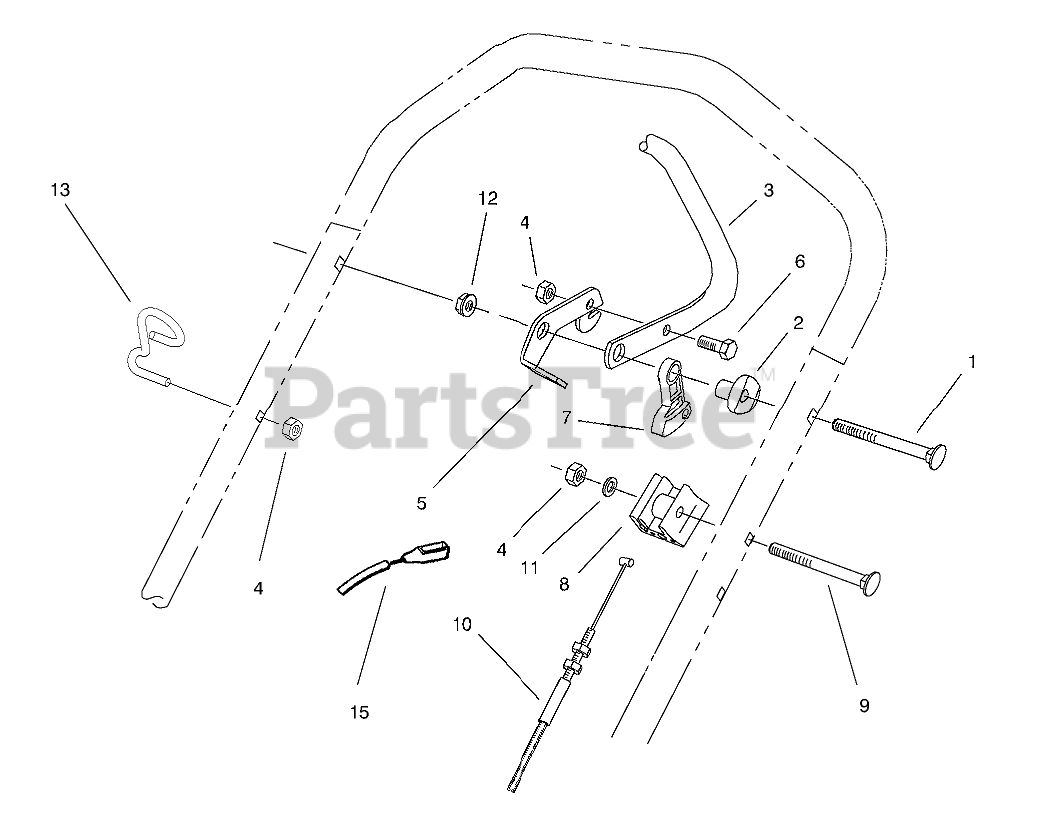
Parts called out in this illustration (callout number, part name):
1	SCREW-HANDLE
2	SPACER-SUPPORT
3	Bar-Control
4	NUT-LOCK, NI
5	LEVER-CONTROL
6	SCREW-HH
7	LEVER-TRACTION
8	SUPPORT-CABLE
9	SCREW-HANDLE
10	CABLE-TRACTION
11	WASHER-FLAT
12	NUT-LOCK, NI
13	GUIDE-ROPE
15	CABLE-BRAKE
